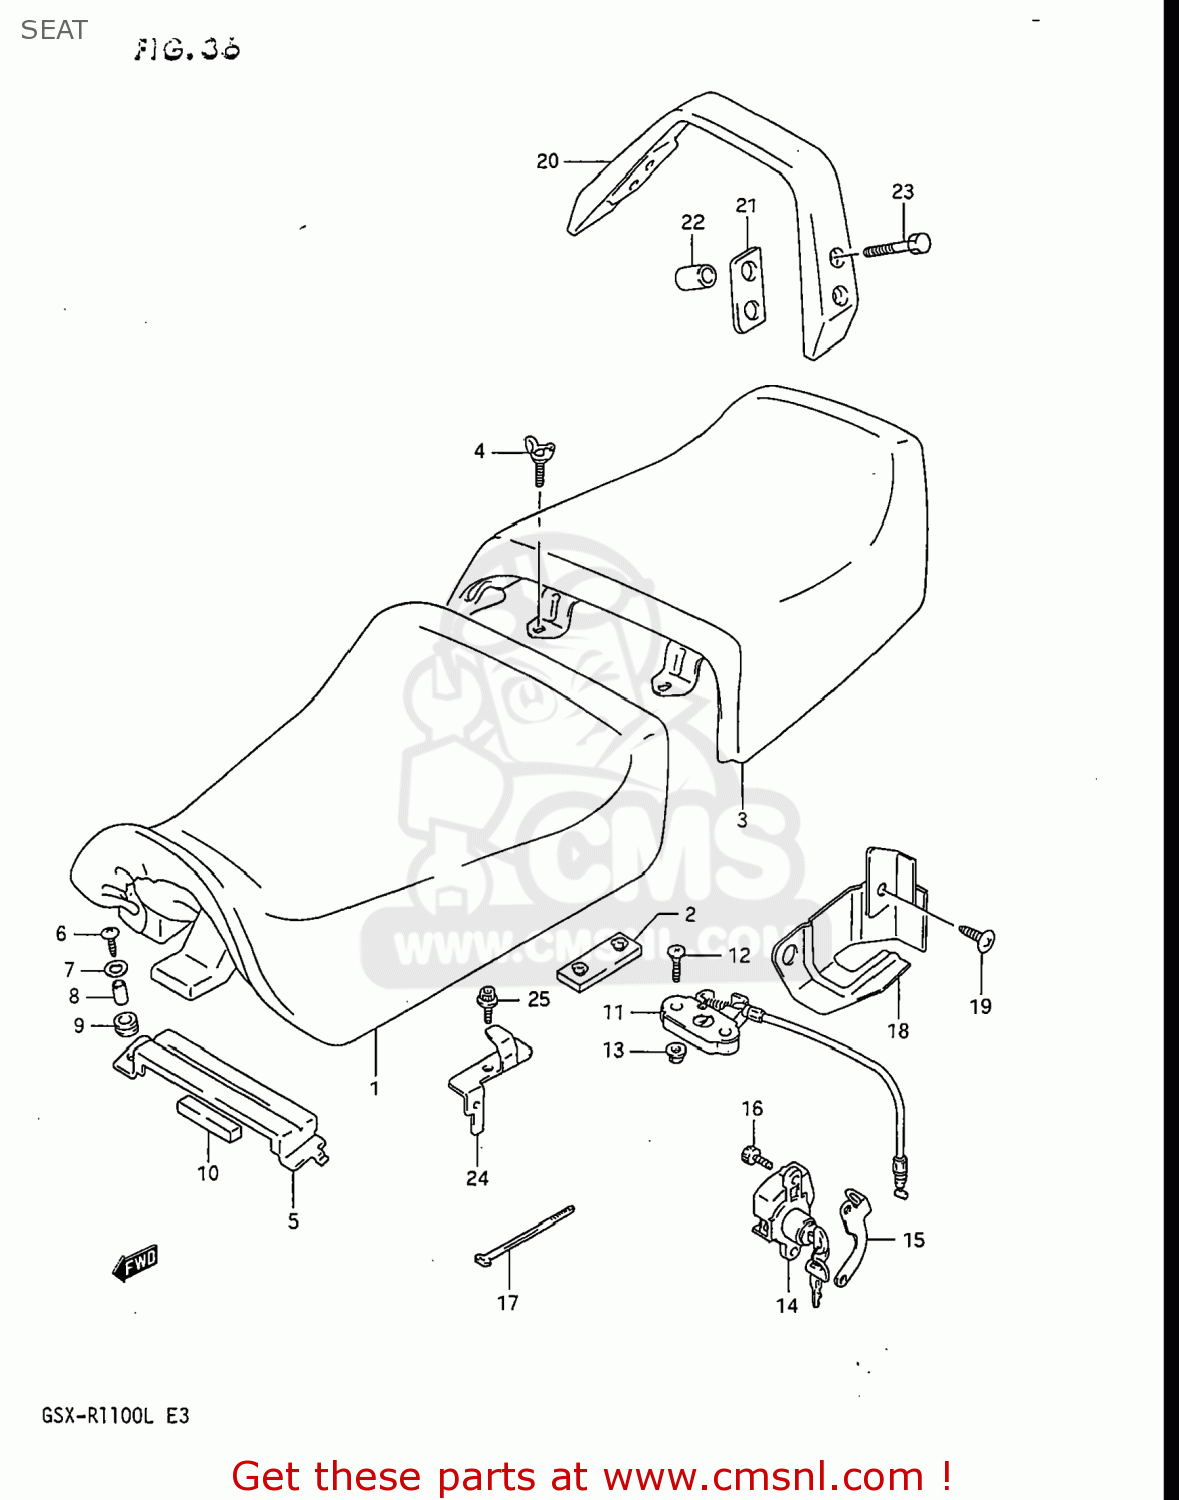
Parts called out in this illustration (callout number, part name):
1	SEAT ASSEMBLY
2	CUSHION,SEAT(40X20X15)
3	SEAT ASSEMBLY,PILLION
4	BOLT
5	PLATE,SEAT SUPPORT,REAR
6	SCREW, CENTER
7	WASHER
8	SPACER (6.1X8X9.5)
9	CUSHION
10	CUSHION,PLATE SEAT SPRING
11	BRACKET,SEAT SUPPORT RR
12	SCREW
13	NUT
14	LOCK SET,SEAT
15	PLATE,SEAT LOCK
16	BOLT
17	CLAMP
18	PLATE,SEAT LOCK CABLE
19	BOLT
20	HANDLE,PILLION RIDER
21	CUSHION,PILLION RIDER HANDLE
22	SPACER(8.6X16X24)
23	BOLT
24	HOLDER,HELMET,RIGHT
25	BOLT
